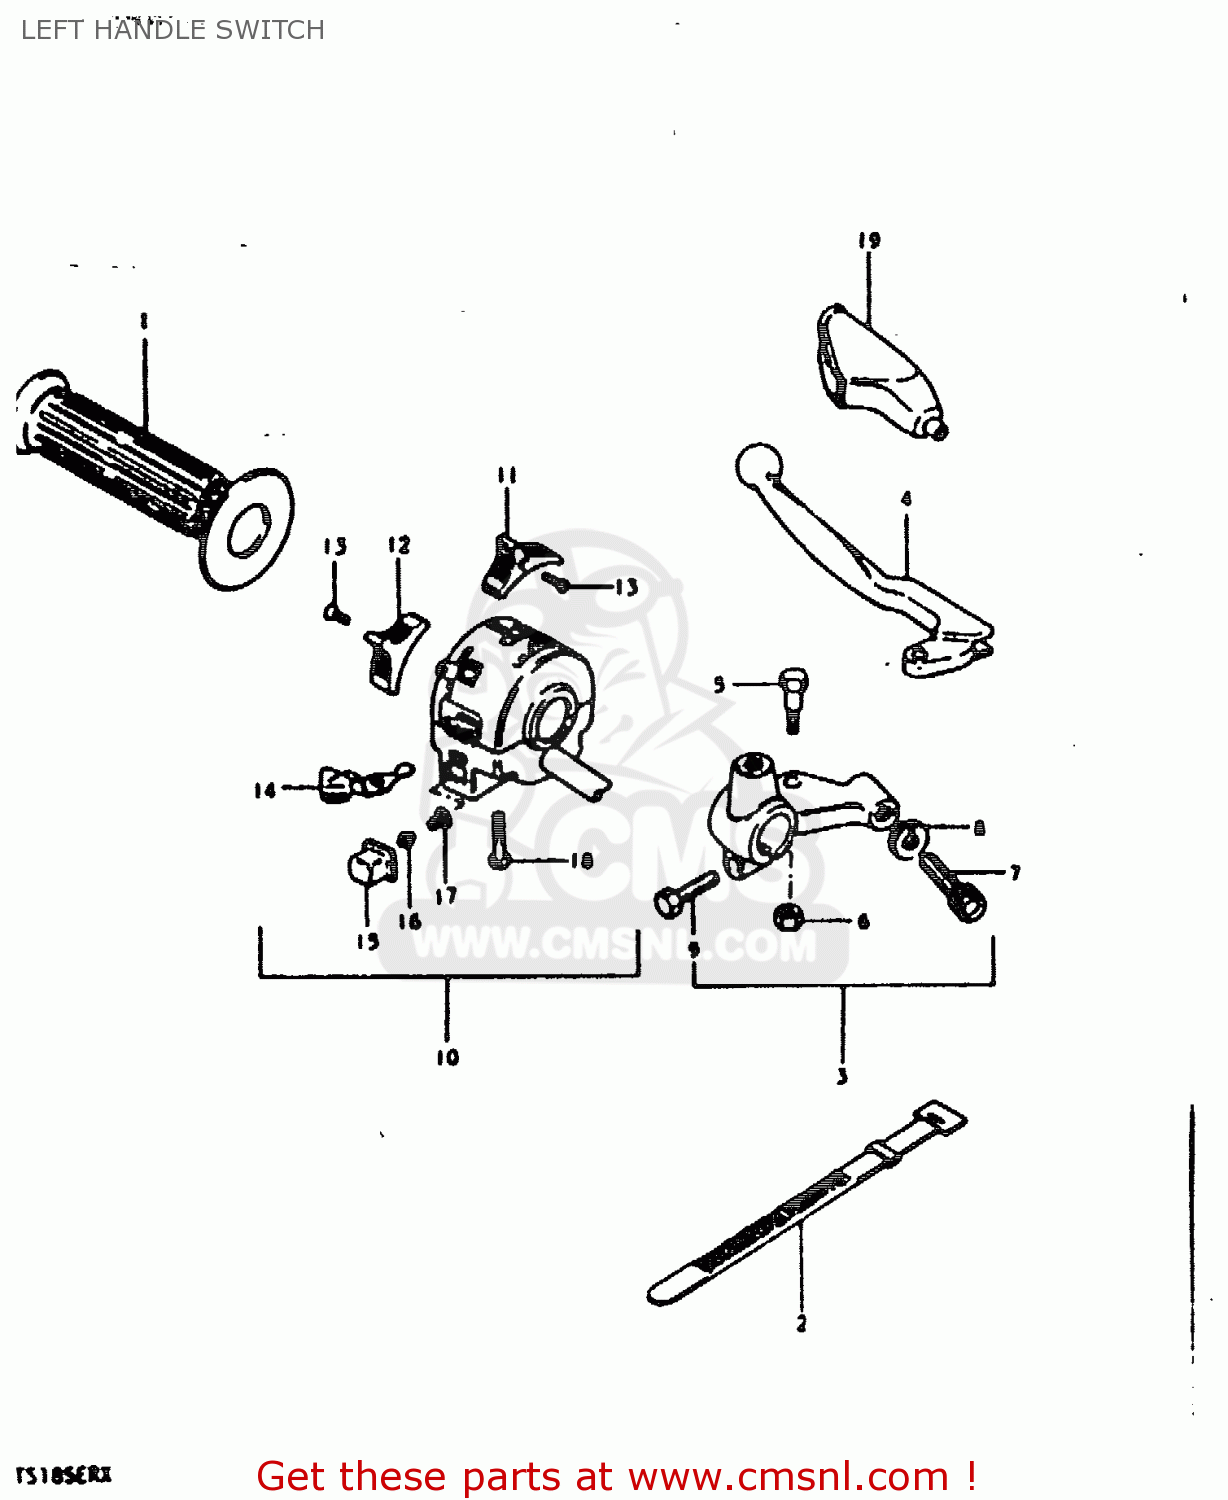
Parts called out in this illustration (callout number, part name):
1	GRIP,L
2	CLAMP(L:120)
3	LEVER ASSY,CLUTCH
4	LEVER,CLUTCH
5	BOLT,LEVER
6	NUT 6MM
7	ADJUSTER,CABLE
8	NUT,CABLE ADJUSTER
9	BOLT
10	SWITCH ASSY, HANDLE LH
11	KNOB,LIGHTING SWITCH
12	KNOB,DIMMER SWITCH
13	SCREW
14	KNOB,TURNSIGNAL
15	BUTTON,HORN
16	CONTACT
17	SPRING
18	SCREW
19	COVER,CLUTCH LEVER
